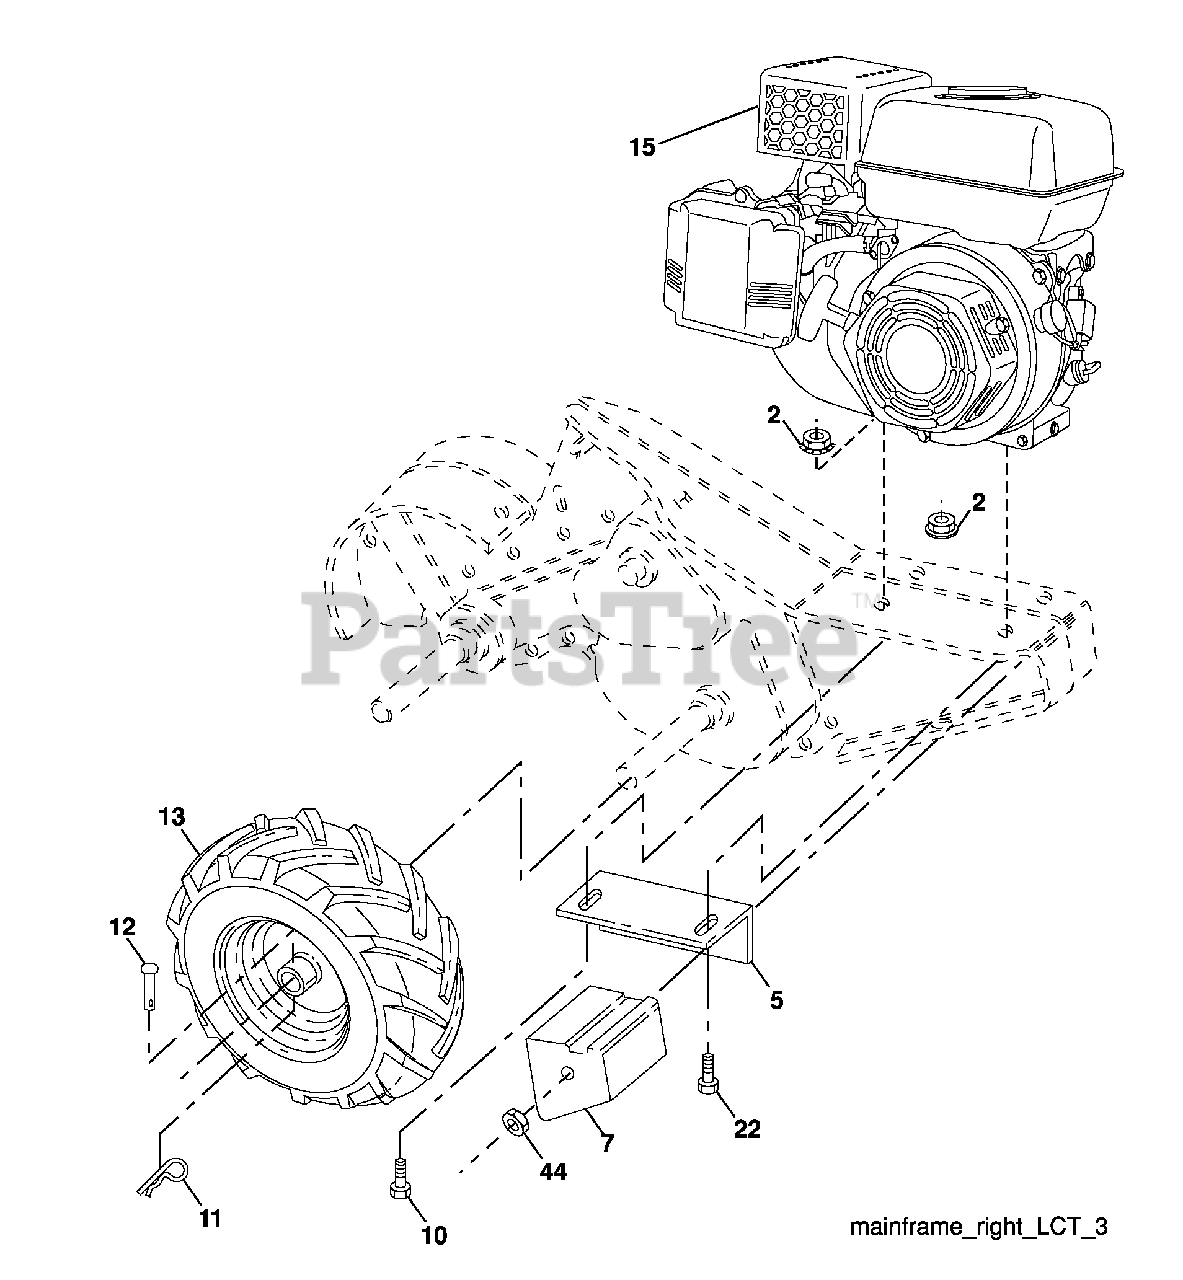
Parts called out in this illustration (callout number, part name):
2	Locknut, Hex, Flange 5/16-18
5	Bracket, Reinforcement RH
7	Counter Weight,
10	Bolt, 5/16-18 x 1-1/2
11	Clip, Hairpin
12	Rivet, Drilled
22	Bolt, Hex 5/16-18 x 1-1/2
44	Nut, Keps Hex 3/8-16 unc
